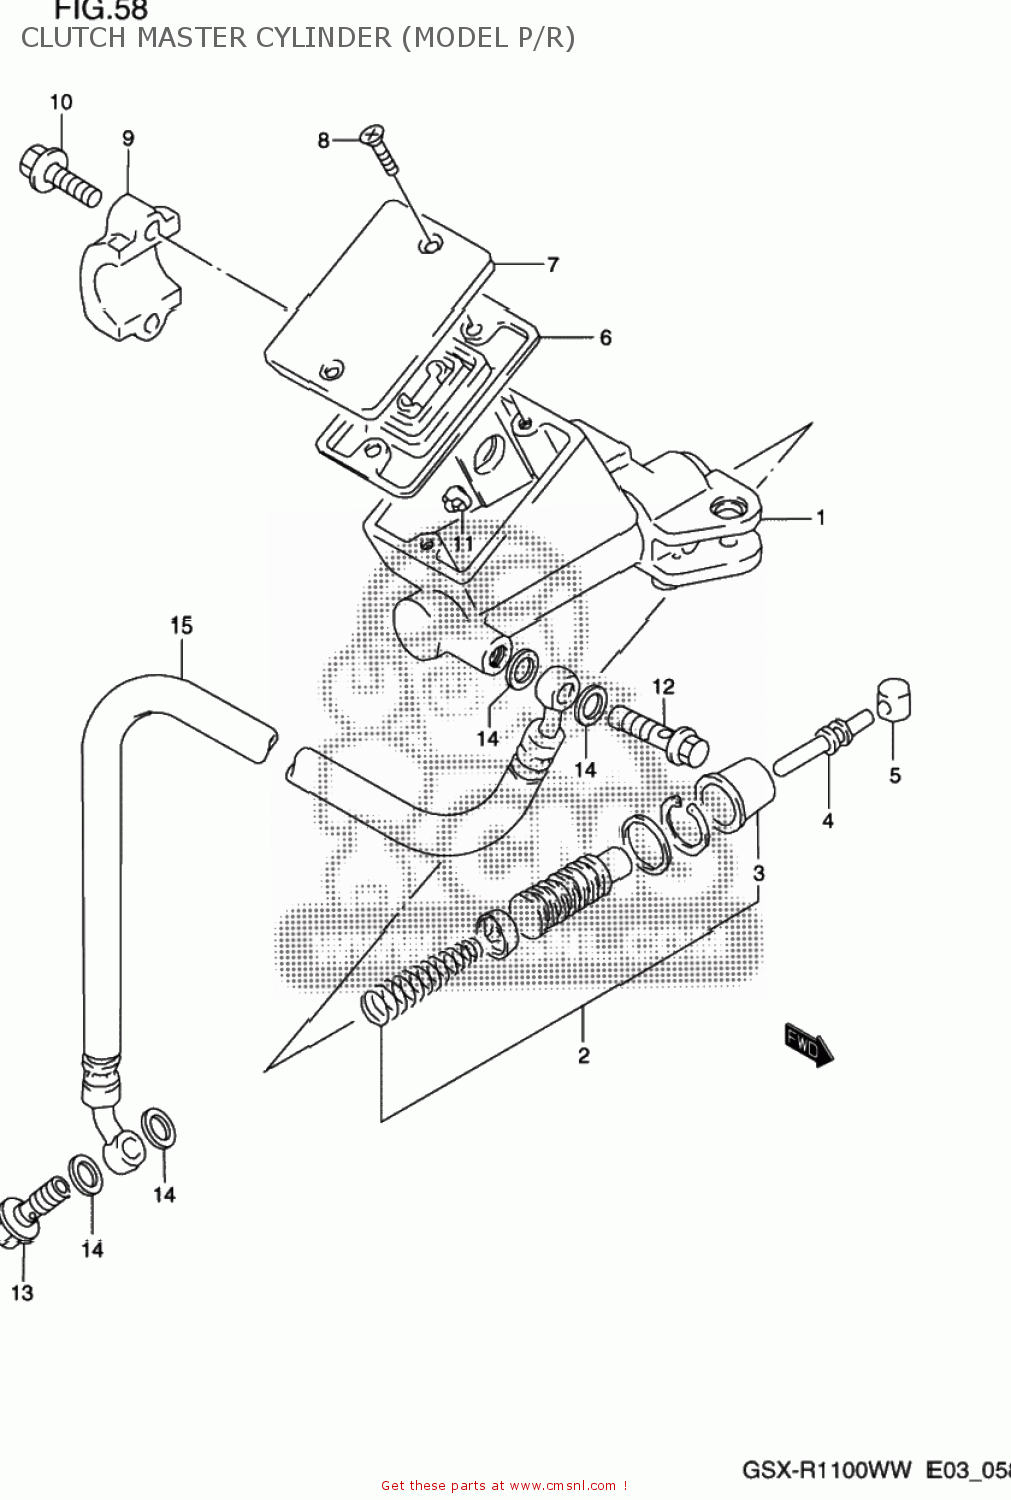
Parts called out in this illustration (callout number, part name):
1	CYLINDER ASSY,CLUTCH MASTER
2	PISTON & CUP SET
3	BOOT
4	ROD,PUSH
5	BUSH
6	DIAPHRAGM
7	CAP
8	SCREW
9	HOLDER
10	BOLT(6X25)
11	PROTECTOR
12	BOLT UNION
13	BOLT UNION
14	WASHER(10X15X1.5)
15	HOSE,CLUTCH
